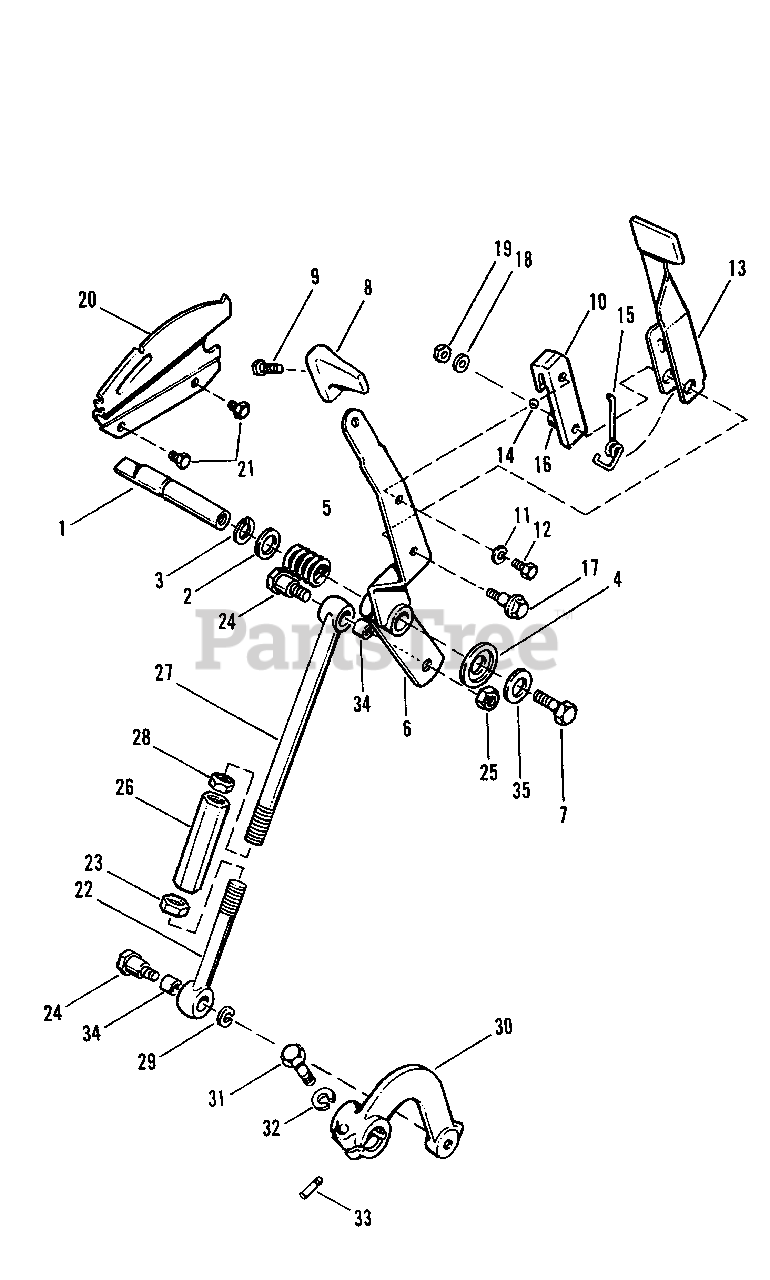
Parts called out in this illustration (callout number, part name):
1	Pivot Shaft
2	Retaining Washer
3	Retaining Ring
6	Speed Control Lever Assembly
7	Hex Capscrew, 3/8"-16 x 1-1/4" lg. Grade 5
9	Thread Forming Screw 1/4"-20 x 3/4" lg.
10	Stop Clamp
11	Lock Washer 1/4"
12	Hex Capscrew, 1/4"-20 x 1/2" lg.
17	Shoulder Bolt
18	Plain Washer, 1/4"
19	Hex Nut, Full, 1/4"-20
21	Thread Forming Screw, 1/4"-20 x 3/8" lg.
23	Hex Nut, Jam, 1/2"-20
24	Shoulder Bolt
25	Hex Nut, Full, Lock,3/8"-16
26	Turn buckle
28	Hex Nut, Jam, 1/2"-20 L.H. Thread
29	Lock Washer, 3/8"
31	Hex Capscrew, 3/8"-16 x 1-1/2" Grade 5
32	Lock Washer, 3/8"
